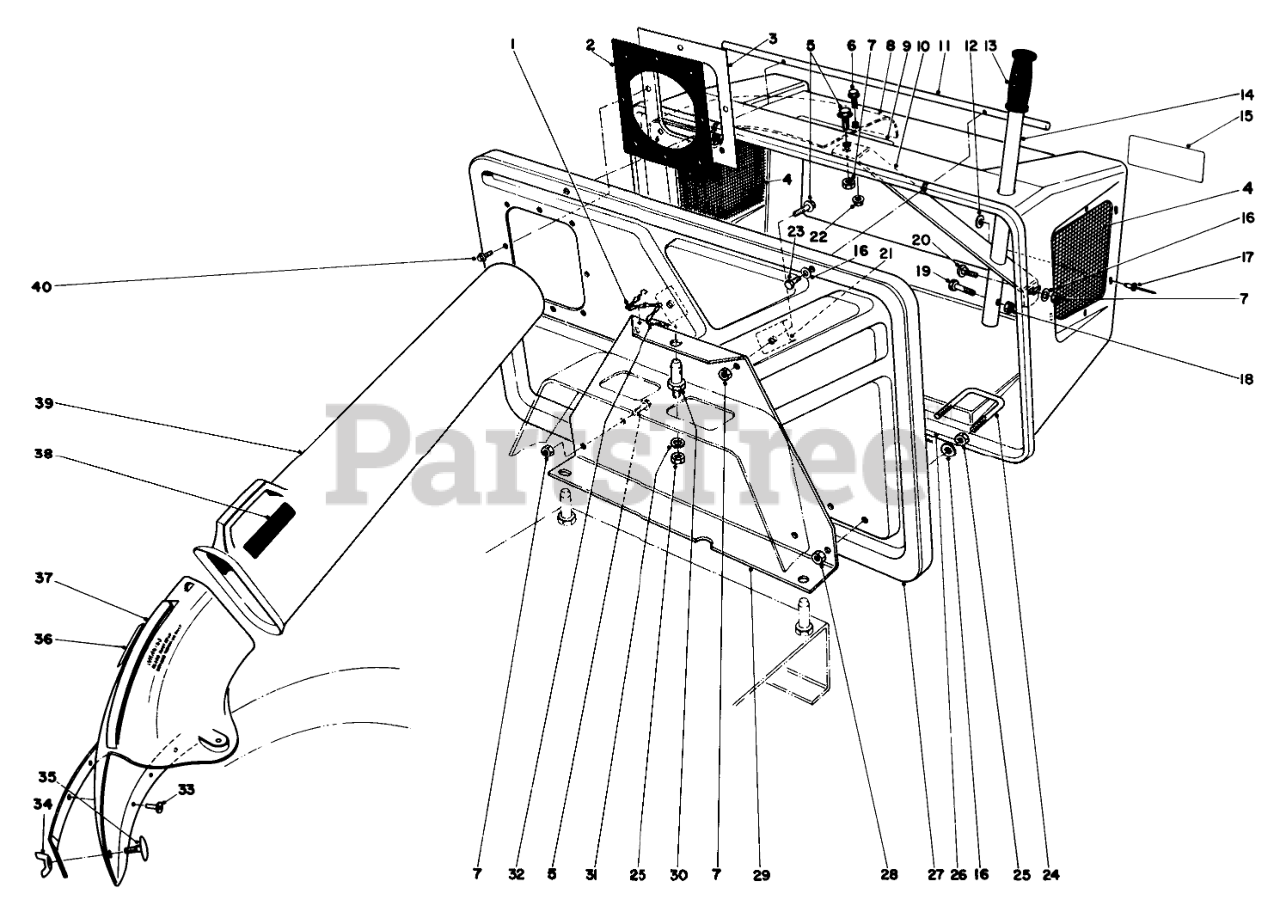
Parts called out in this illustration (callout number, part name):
1	6-LINK CHAIN W/HOOK
2	INLET SEAL
3	FRAME SEAL
4	SCREEN
5	SCREW-HHF
6	SCREW-HWH
7	NUT-HEX, SIDE DEFORM
8	DEFLECTOR
9	DECAL
10	HANDLE GUIDE
11	PIVOT ROD
12	WASHER-FLAT
14	HANDLE TUBE
15	EASY EMPTY BAG DECAL
16	WASHER-FLAT
17	RIVET-POP
18	NUT-HEX, SIDE DEFORM
19	SCREW-HH
20	SCREW-CARR
21	Retainer
22	NUT-LOCK, FLANGE
23	SCREW-HH
24	LATCH
25	NUT-HEX
26	HOPPER
28	NUT-LOCK, NI
29	Plate Mounting
30	Pin-Mounting
31	WASHER-LOCK
32	HAIRPIN COTTER
33	RIVET 3/16 X 7/16
34	NUT-WING
35	STEP BOLT
36	Decal-Chute
37	Chute Assembly (Incl. Ref. #32 & 35)
38	Decal Duct
39	Duct Assembly (Incl. Ref. #37)
40	SCREW
